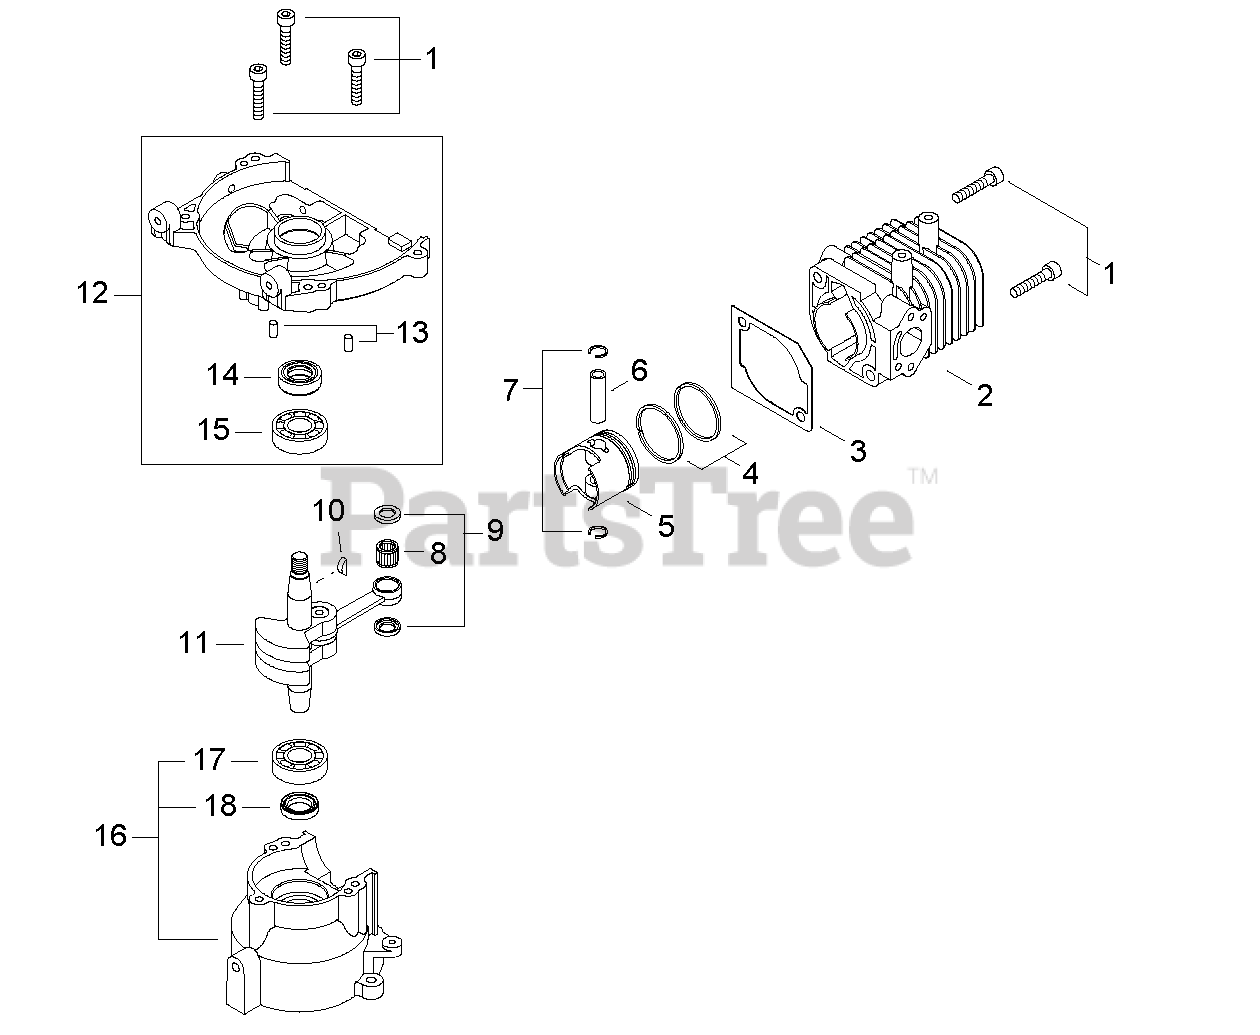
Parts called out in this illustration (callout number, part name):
1	BOLT 5×25
2	CYLINDER
3	GASKET, CYLINDER
4	RING, PISTON
6	PIN, PISTON 8
7	RING, SNAP
8	BEARING, NEEDLE 8
9	WASHER, THRUST 8
10	KEY, WOODRUFF 3×10
11	CRANKSHAFT ASSY
12	CRANKCASE ASSY, M
13	PIN, LOCATING Ø4×8
14	SEAL, OIL 12
15	BEARING, BALL 6001 C3
16	CRANKCASE ASSY, PTO
17	BEARING, BALL 6001 C3
18	SEAL, OIL 12
